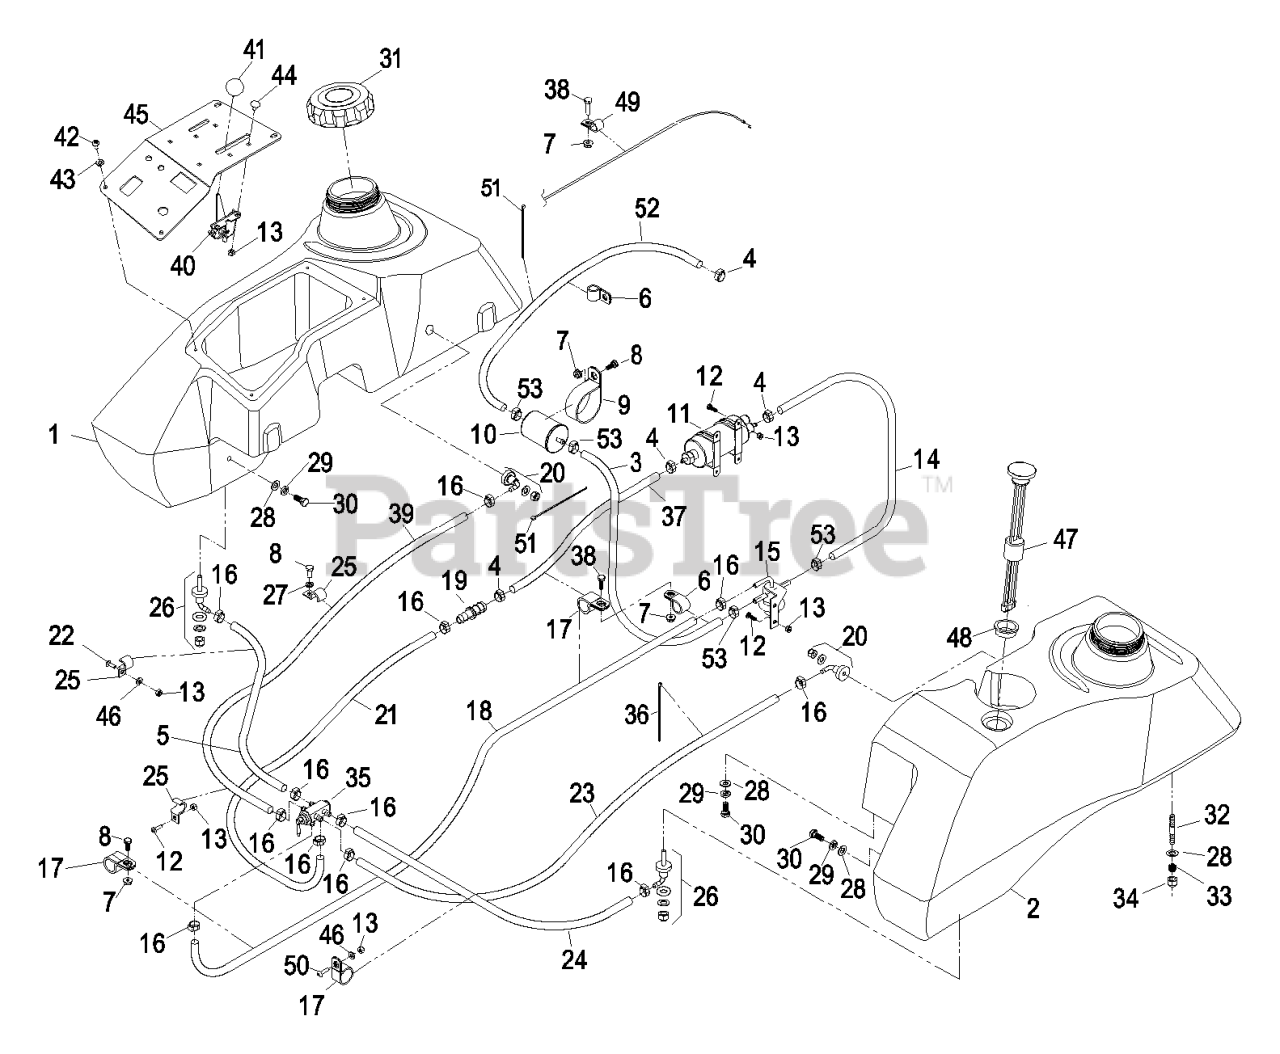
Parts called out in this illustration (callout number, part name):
4	CLAMP-HOSE, FUEL
6	CLIP-LOOM
8	SCREW-HH
9	CLIP-LOOM
10	Fuel Filter (Large)
11	Fuel Pump
12	SCREW-PPH
13	NUT-LOCK, NI
15	Fuel Regulator
16	CLAMP-HOSE, FUEL
17	CLIP-LOOM
19	CONNECTOR
20	FITTING-FUEL, BULKHEAD
21	HOSE-FUEL
22	BOLT-CARR
24	HOSE-FUEL
25	CLIP-HALF, LOOM
26	FITTING-FUEL, BULKHEAD
27	WASHER-LOCK
28	WASHER-PLAIN
29	WASHER-LOCK
30	SCREW-HH
32	STUD
33	SPRING-TANK, FUEL
34	NUT-LOCK, NI
35	VALVE-FUEL, DUAL FLOW
36	TIE-CABLE
37	HOSE-FUEL
38	SCREW-HH
40	CABLE-THROTTLE
41	KNOB-BALL
42	SCREW-PTH
43	WASHER-SPRING
44	BOLT-CARR
46	WASHER-FLAT
48	CONTACT ORDER SERVICES
49	CLIP-LOOM
50	SCREW-HEAD, TRUSS
51	TIE-PLASTIC
52	KIT, EFI FILTER-ENG FUEL
53	CLAMP
